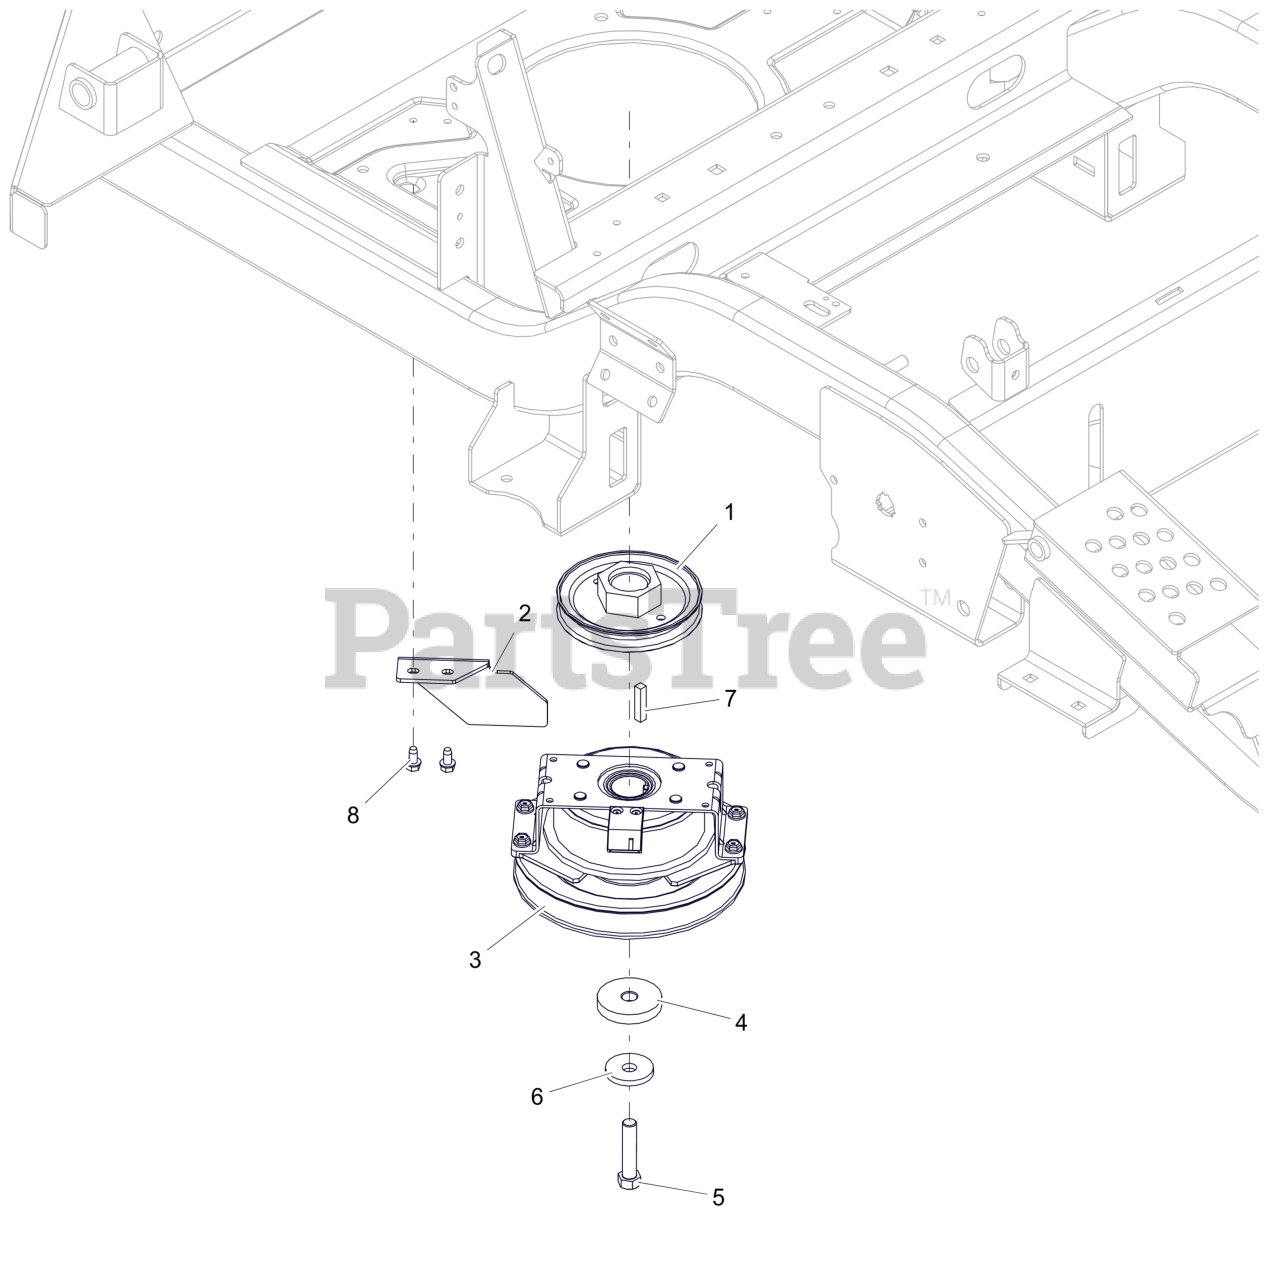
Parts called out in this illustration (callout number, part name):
1	WLDMT,PULLEY-4.50ODX1.127
2	BRKT, CLUTCH STOP HD
3	CLUTCH, OGURA DBLS SPRG 1.13"
4	SPACER, .474/.459X2.00X.350
5	BLT, HEX 0.4375-20X2 G8 ZCC NT
6	WASHER, 7/16" SPRING DISK
7	KEY-SQ .25 X 1.25 X .25 SAE
8	SCR-TAP .25-20X.50 HWH ZCC
